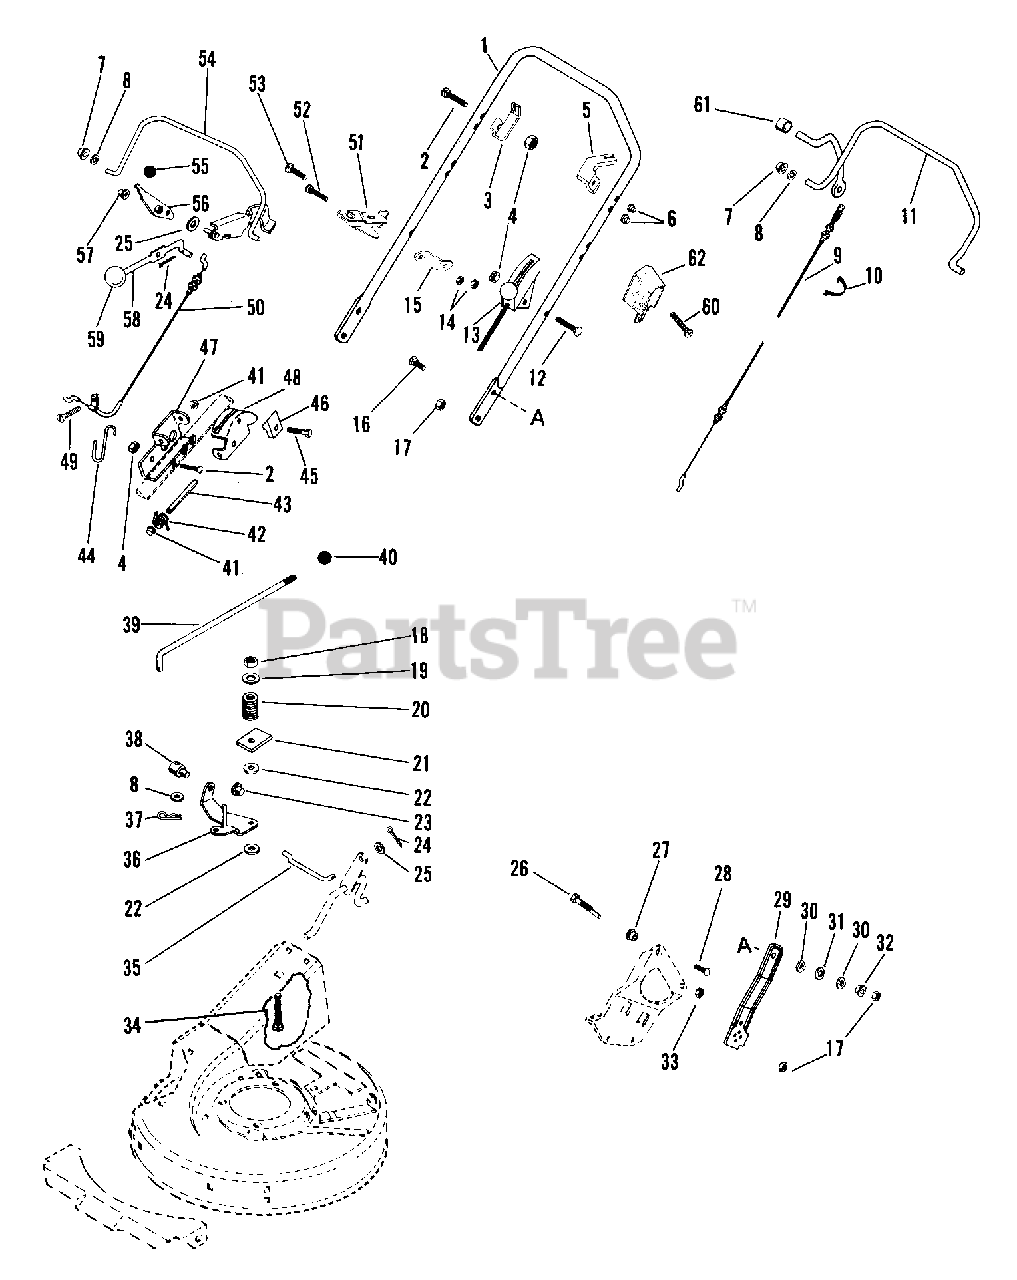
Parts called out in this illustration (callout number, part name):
1	HANDLEBAR
2	BLT-RDHDSQNK .25-20X1.25 XLGPL
3	CABLE ANCHOR
4	NUT-KEPS .250-20
5	CABLE ANCHOR - LH
5	CABLE ANCHOR-LH
6	NUT-PUSH .312 DIA. PAL
7	BSHG-FLG .325X.444X.440X.560
8	WSHR-FL-STL.344X.688X.065PL
9	CABLE,TRACTION
9	CABLE, TRACTION
10	CABLE RETAINER
10	CABLE TIE LG 5-1/2
11	TRACTION BAIL-COATED
12	BLT-RDHDXLSQNK .25-20X2.0 G5YZ
13	CABLE,THROTTLE W/CHOKE
13	CABLE,THROTTLE
14	NUT-LK-CTR .250-20 PL
15	BRACE-SPEED CONTROL
16	BLT-RDHDSQNK .31-18X1.12 GR5PL
17	NUT-LK-TOP .312-18 GR C PL
18	NUT-LK-CTR .375-16 GR A PL
19	WSHR-FL-STL.406X.812X.065PL
20	SG-COMP .187X.56X1.62
21	PRESSURE FLANGE
21	FRICTION WASHER
23	CAP, 3/8 ROD YWZC
24	PIN-COTR .06X.50
25	WSHR-FL-STL.281X.62X.065 PL
26	HANDLEBAR STUD
27	BSHG, FLG .325X.499X.26X.88
28	BLT-RDHDSQNK.31-18X.88 GR5YWZC
29	HANDLEBAR BRACKET
29	HANDLEBAR ADJUSTMENT LINK LH
29	LINK,HANDLE BAR ADJUST LH
29	HANDLEBAR ADJUSTMENT LINK RH
29	LINK,HANDLE BAR ADJ RH
30	WAVE WASHER .531X.781X.125FH
30	WASHER,BELLEVILLE SPRING
31	WSHR-FL-STL .520X.810X.033
32	BSHG-FLG .325X.500X.513X.875
33	NUT-LK-JAM-CTR .375-16 PL
34	BLT-RDHDSQNK .38-16X2.00 SHTYW
35	SHIFT LINK
36	BELL CRANK - SPEED CONTROL
37	PIN-HAIR INT .08X.18X1.18
38	SWIVEL
39	ROD-SPEED CONTROL
40	KNOB, BALL 5/16-18 X 1.5
41	PUSH NUT, .188
42	SG-TORS .062X.28X1.00
43	PIN,BBC LATCH
44	CABLE RETAINER
45	SCR-TAP 10-24X.375 CRPH PL 1A
46	KNOB
47	BBC LATCH PIVOT
48	BBC LATCH
49	SCR-MCH 10-32X.25 CR SEMS PL
50	CABLE,ENG. SACHS
50	CABLE,ENG. B&S
50	CABLE,BBC
50	CABLE, BBC
50	CABLE-BBC
50	CABLE-ENG. CONTROL
50	CABLE,ENGINE
50	CABLE,ENG. COMMERCIAL
51	BRACKET-SPEED CONTROL
52	BLT-RDHDSQNK .25-20X1.50 SHTPL
53	@BLT-RHDSSQNK .25-20X.38 G2YZ
54	START BAIL WELDMENT
54	START BAIL WELDMENT-ELEC.
54	BBC BAIL
54	START BAIL-SACHS
55	KNOB, CONTROL-THROTTLE
56	START LEVER WELDMENT
57	PUSH NUT, .25
58	CHOKE HANDLE-SACHS
59	KNOB
60	SCR-MCH 10-32X.50 CRFLSTRSEMS
61	CAP, VINYL, .25 ID
62	SWITCH-CABLE ANCHOR
62	SWITCH-CABLE ANCHOR WELDMENT
